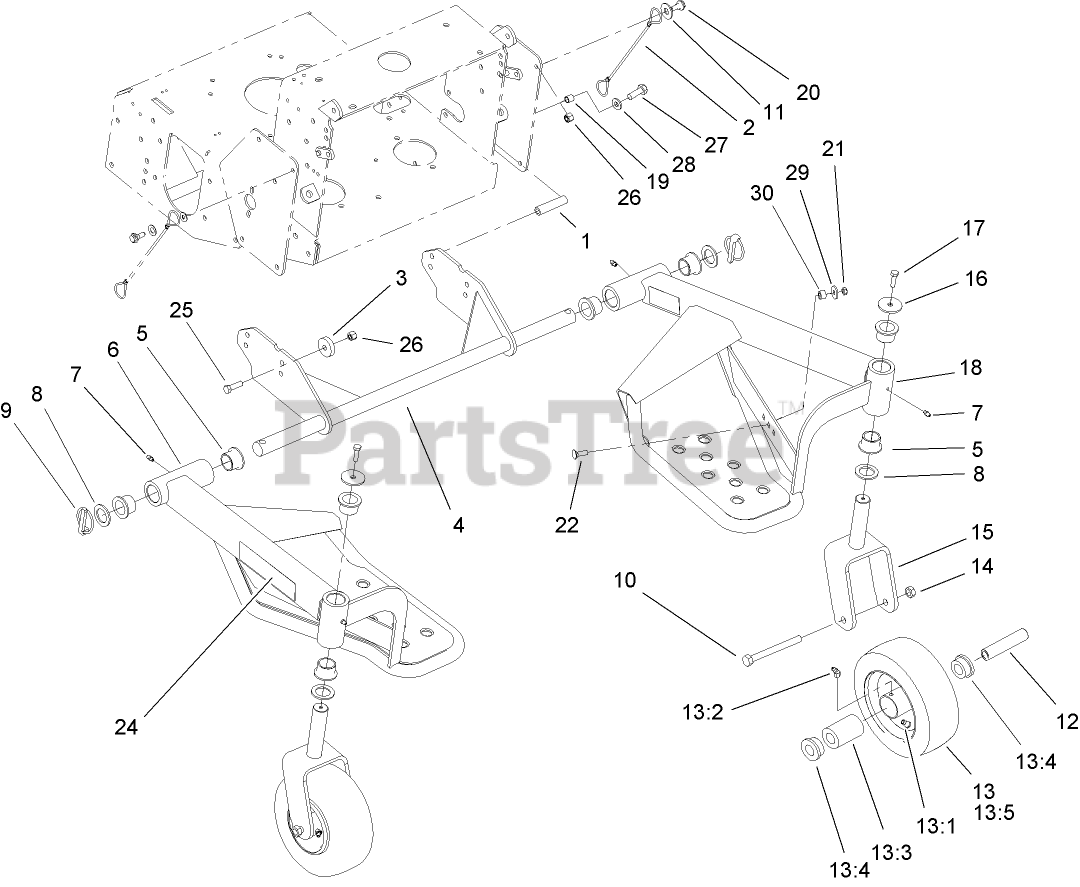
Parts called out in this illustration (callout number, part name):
1	SPACER-SHIELD (Used on hydro units only)
2	LANYARD
3	SPACER (Used on gear drive units only)
4	AXLE-SULKY
5	BUSHING
6	LH FLOOR PLATE ASM
7	FITTING-GREASE
8	WASHER-THRUST
9	PIN-LYNCH
10	SCREW-HH
11	WASHER-FLAT
12	BUSHING-SPANNER
13	CASTER WHEEL ASM
13:1	STEM-VALVE
13:2	FITTING-LUBE, 45 DEG
13:3	BEARING
13:4	BEARING-OUTSIDE
13:5	TIRE-TUBELESS
14	NUT-HEX
15	CASTOR ASM
16	WASHER-REBOUND
17	SCREW-HH
18	RH FLOOR PLATE ASM
19	SPACER-SHORT (Used on hydro units only)
20	SCREW-SHOULDER, HWH
21	NUT-LOCK, NI
22	BOLT-CARR
25	SCREW-HH (Used on gear drive units only)
26	NUT-LOCK, NI
27	SCREW-HH
28	WASHER-FLAT
29	Washer-Friction
30	SPACER
